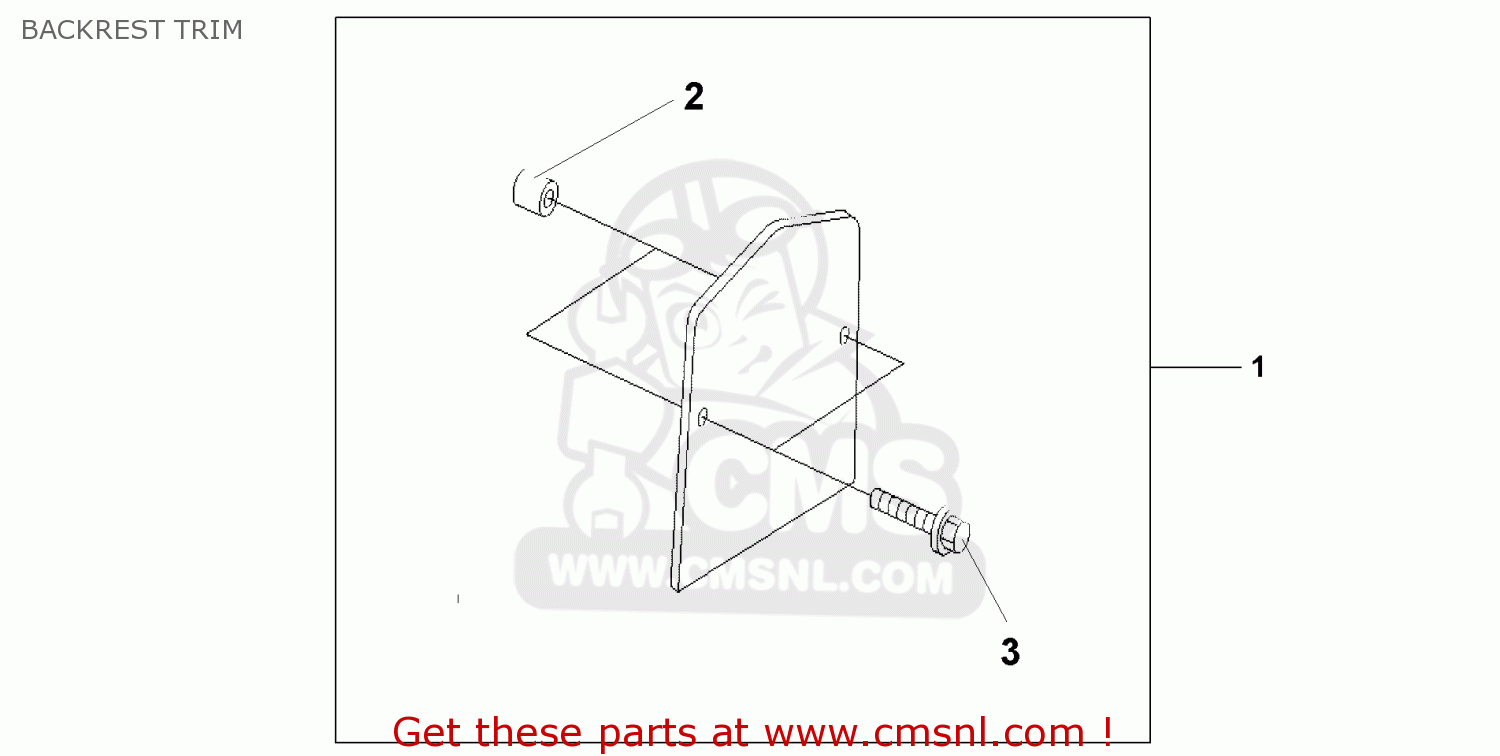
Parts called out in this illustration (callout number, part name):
1	BACKREST TRIM
2	COLLAR,CABLE CLAM
3	BOLT,FLANGE,6X22
